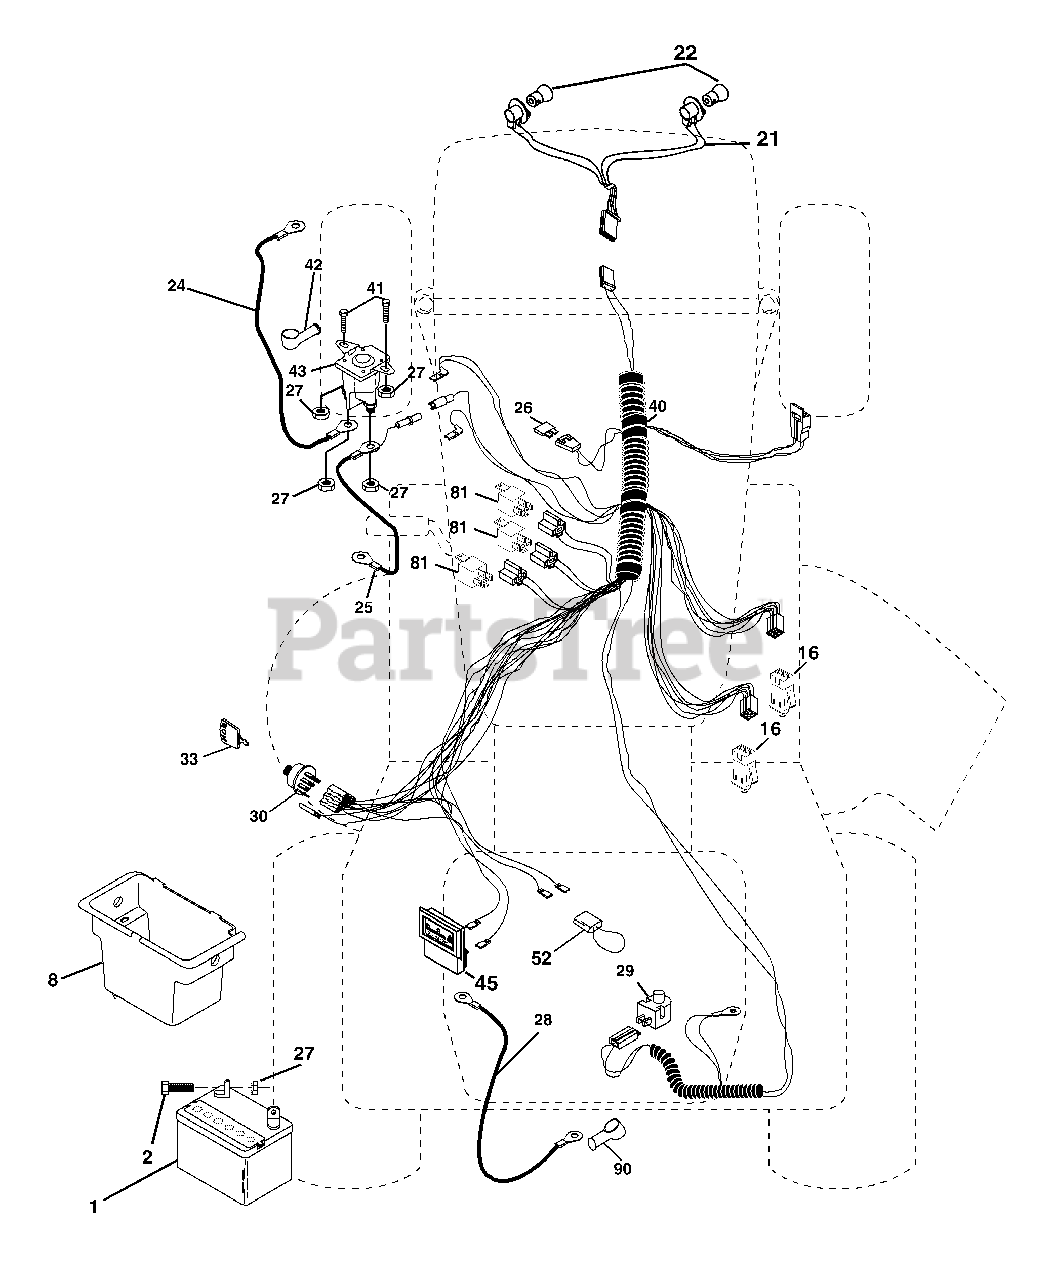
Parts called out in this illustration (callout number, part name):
1	Battery 12 Volt 25 Amp
2	Bolt Hex Hd 1/4-20 Unc x 3/4
8	Box Battery
16	Switch Interlock
21	Harness Asm Light W/4152J
22	Bulb Light #1156
24	Cable Battery 6 Ga 11" red
25	Cable Battery 6 Ga w/16 wire,red
26	Fuse 20 AMP
27	Nut Keps Hex 1/4-20 Unc
28	Cable Ground 6 Ga 12" black
29	Switch Plunger
30	Switch Ign
33	Key Ign
40	Harness Ign
41	Bolt Blk Fin Hex 1/4-20 x 1/2
42	Cover Terminal Red
43	Solenoid
45	Ammeter
52	Protection Wire Loop
81	Relay Asm.
90	Cover Terminal
